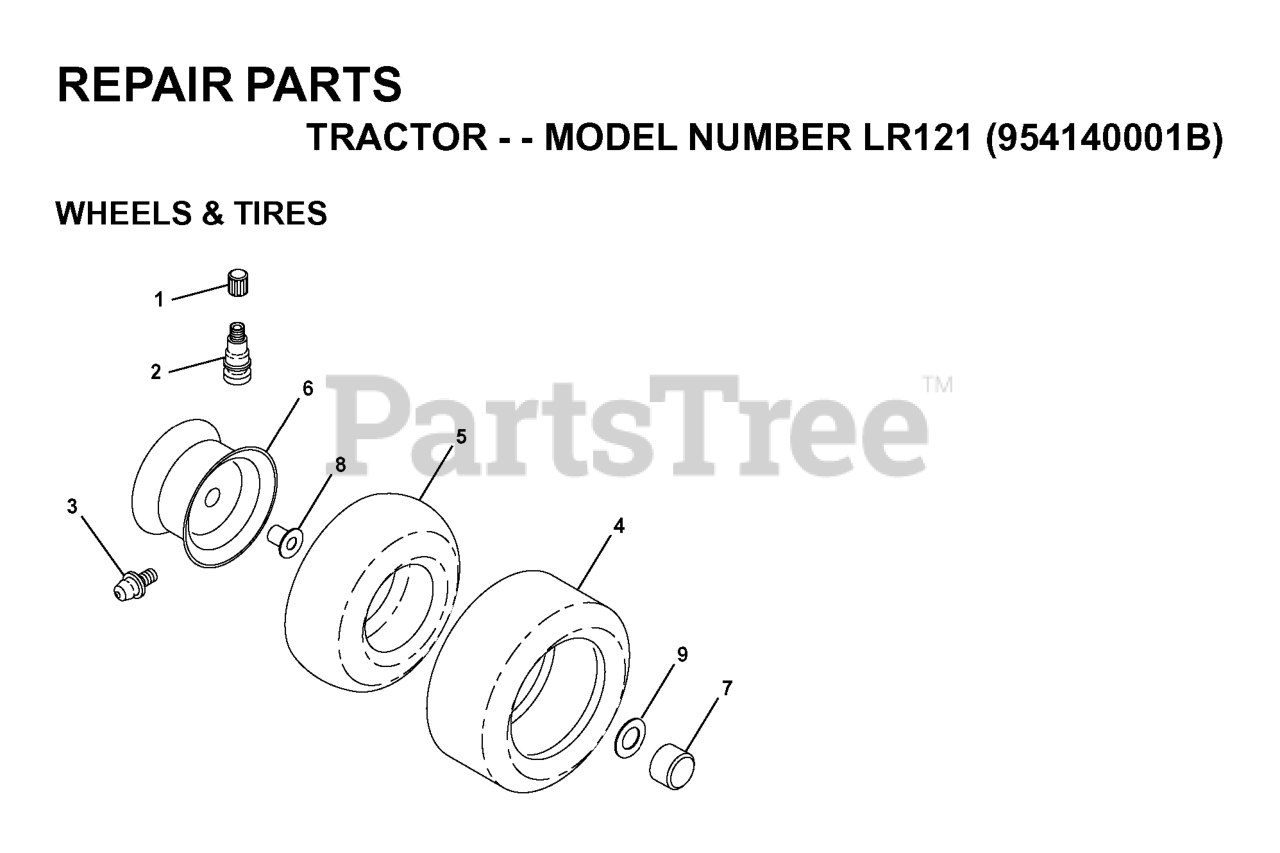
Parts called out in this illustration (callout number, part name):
2	VALVE STEM LT
3	FITTING LT
4	TIRE HEAVY DUTY
4	TIRE.13X5-6.TURF.SAVER.FRONT
5	TUBE.16X6.5/7.5-8
5	TUBE.5.3/4.5/6
6	RIM REAR 8"
6	RIM
7	CAP.HUB.FRONT.LT.BLACK
8	BEARING T
